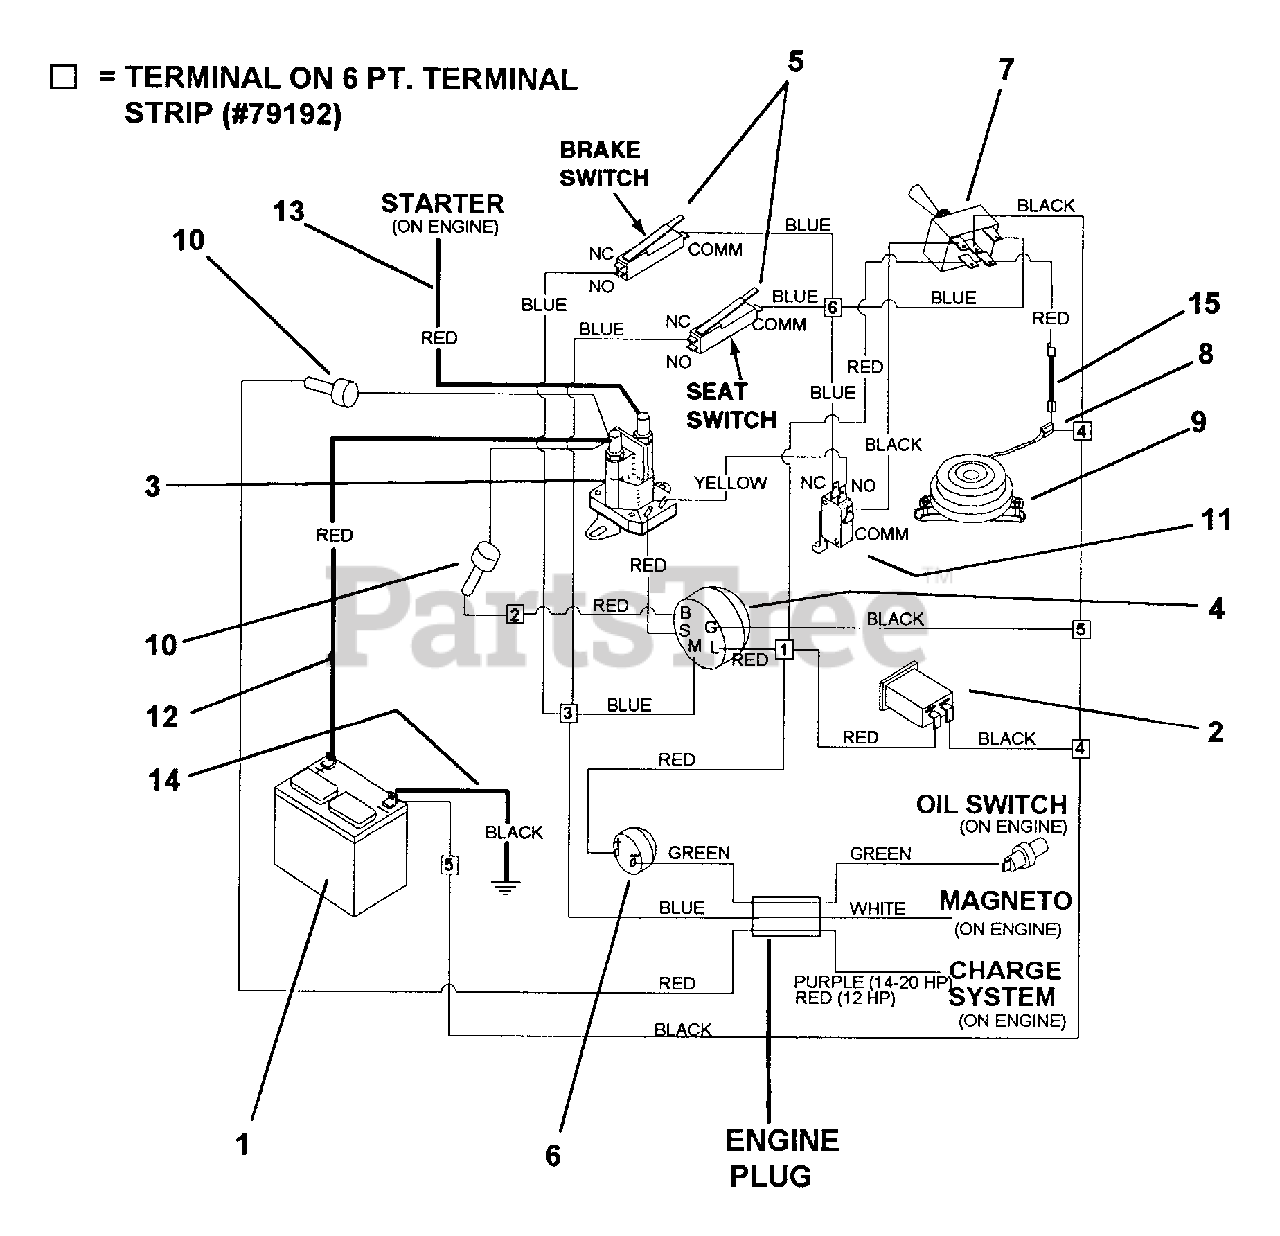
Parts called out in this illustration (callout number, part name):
1	BATTERY
2	HOUR METER
3	SOLENOID
4	START SWITCH
5	SWITCH, ENCL, SPDT 15A HINGED LEVER
6	BUZZER
7	CLUTCH SWITCH
8	INSULATOR COVER (female end only)
9	ELECTRIC CLUTCH
10	FUSE HOLDER (INLINE)
11	SWITCH, SPDT MINIATURE
12	CABLE, BATTERY, 31.75" W/ BOOTS
13	CABLE, STARTER, 31.75" W/O BOOTS
14	WIRE ASS'Y, 24" BLK. 8 GA. ENG./GRD., 20 HP
15	CLUTCH WIRE EXTENSION
